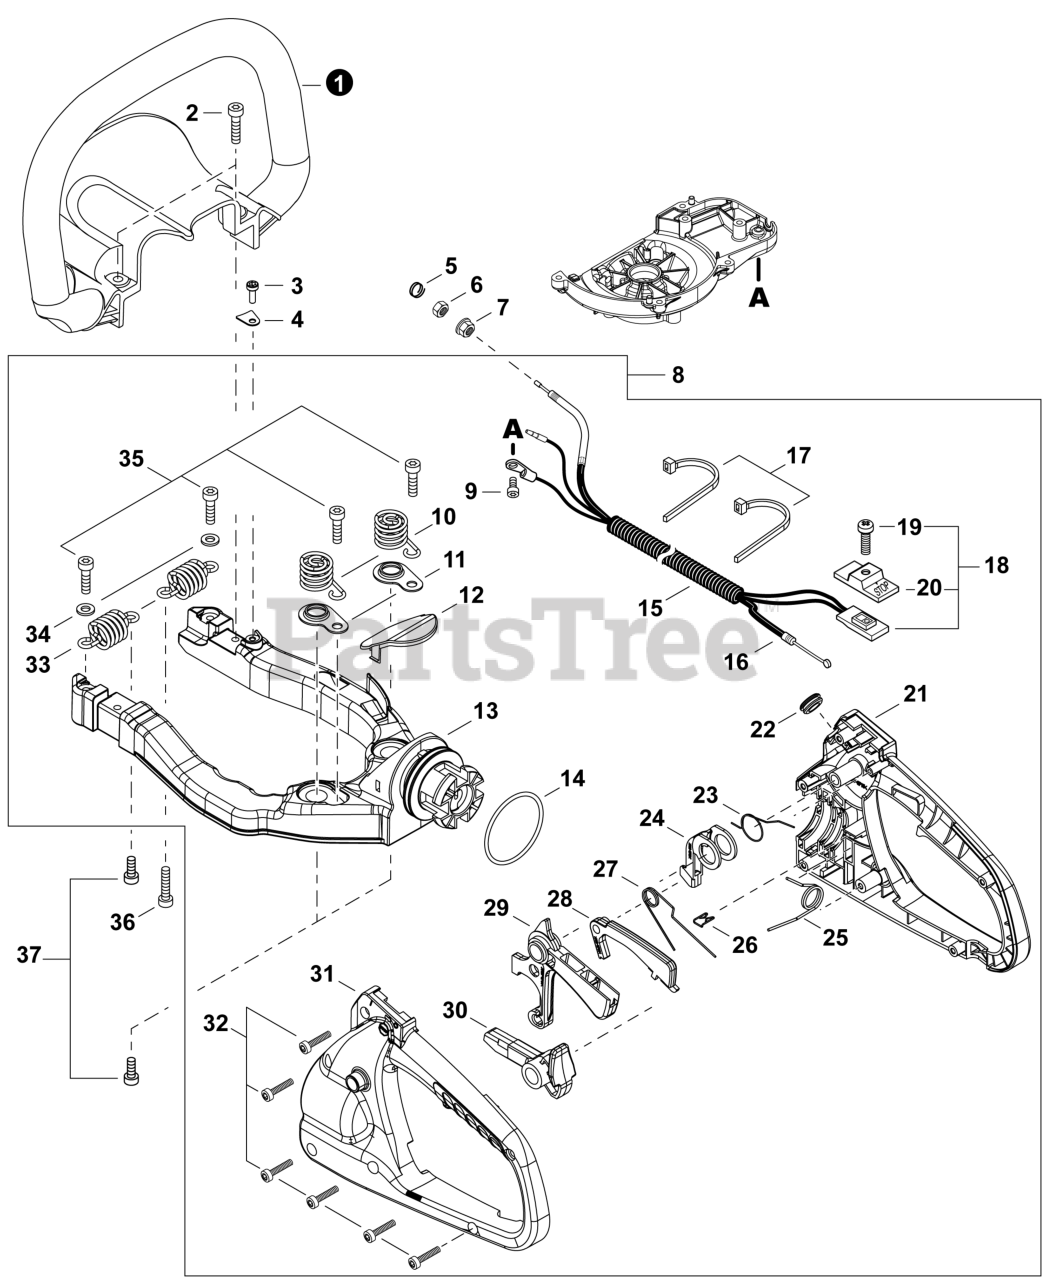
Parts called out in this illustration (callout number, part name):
1	HANDLE, FRONT
2	BOLT, TORX 6x25
3	BOLT, TORX 4x12
4	PLATE, EYE
7	NUT, FLANGE M6
8	HANDLE ASSY, REAR
9	BOLT, TORX 4x10
10	SPRING, COMPRESSION
11	HOLDER, SPRING
12	COVER, HANDLE
15	TUBE, PROTECTIVE
16	CABLE, THROTTLE
17	STRAP, CABLE
18	SWITCH, ON-OFF
19	SCREW 3x10
20	KNOB, SWITCH - ORANGE
21	HANDLE, RIGHT REAR
22	GROMMET
23	SPRING, COIL
24	LEVER, THROTTLE
25	SPRING, TORSION
27	SPRING, TORSION
28	LOCKOUT, THROTTLE
29	TRIGGER, THROTTLE
30	LEVER, HANDLE RELEASE
31	HANDLE, LEFT REAR
32	BOLT, TORX 4x16
33	SPRING, COMPRESSION
35	BOLT, TORX 6x20
36	BOLT, TORX 6x25
37	BOLT, TORX 6
